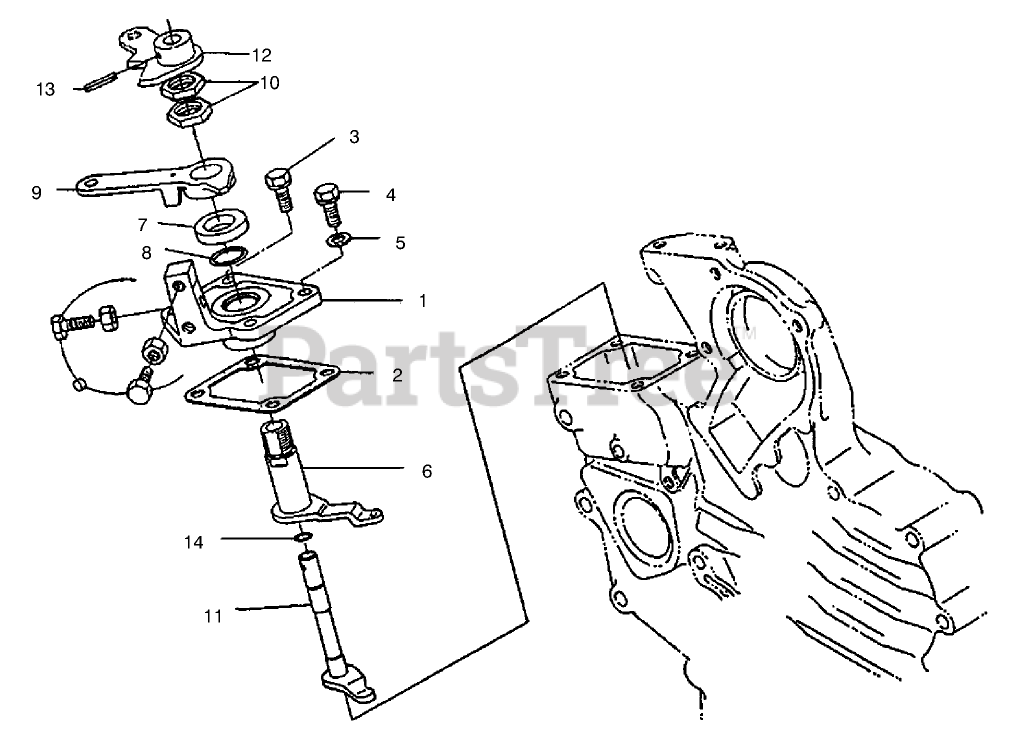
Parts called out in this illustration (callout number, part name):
1	PLATE-SPEED, CONT.
2	GASKET
4	BOLT
5	GASKET
6	LEVER-GOVERNOR
7	COLLAR
8	O-RING
9	LEVER-CONT., SPEED
11	SHAFT-LEVER
12	LEVER-STOP, ENGINE
13	PIN-SPRING
14	O-RING
